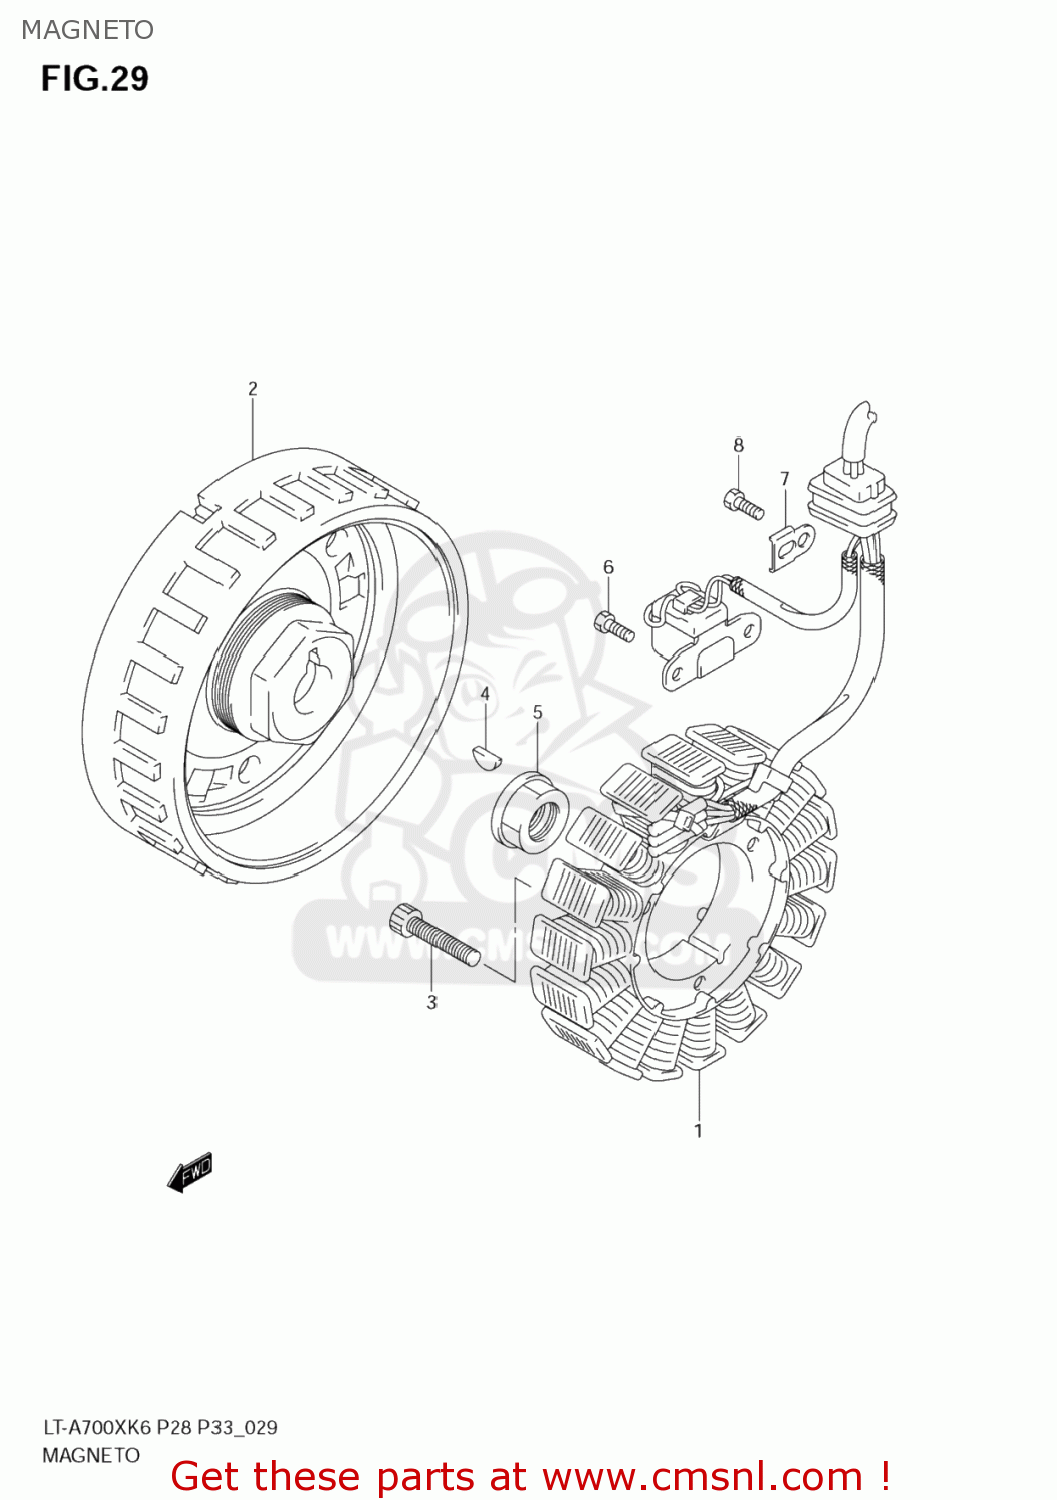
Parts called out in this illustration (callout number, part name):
1	STATOR ASSY
2	ROTOR ASSY
3	BOLT
4	KEY
5	NUT,MAGNETO ROTOR
6	BOLT(5X10)
7	CLAMP,GENERATOR LEAD WIRE
8	BOLT(5X10)
